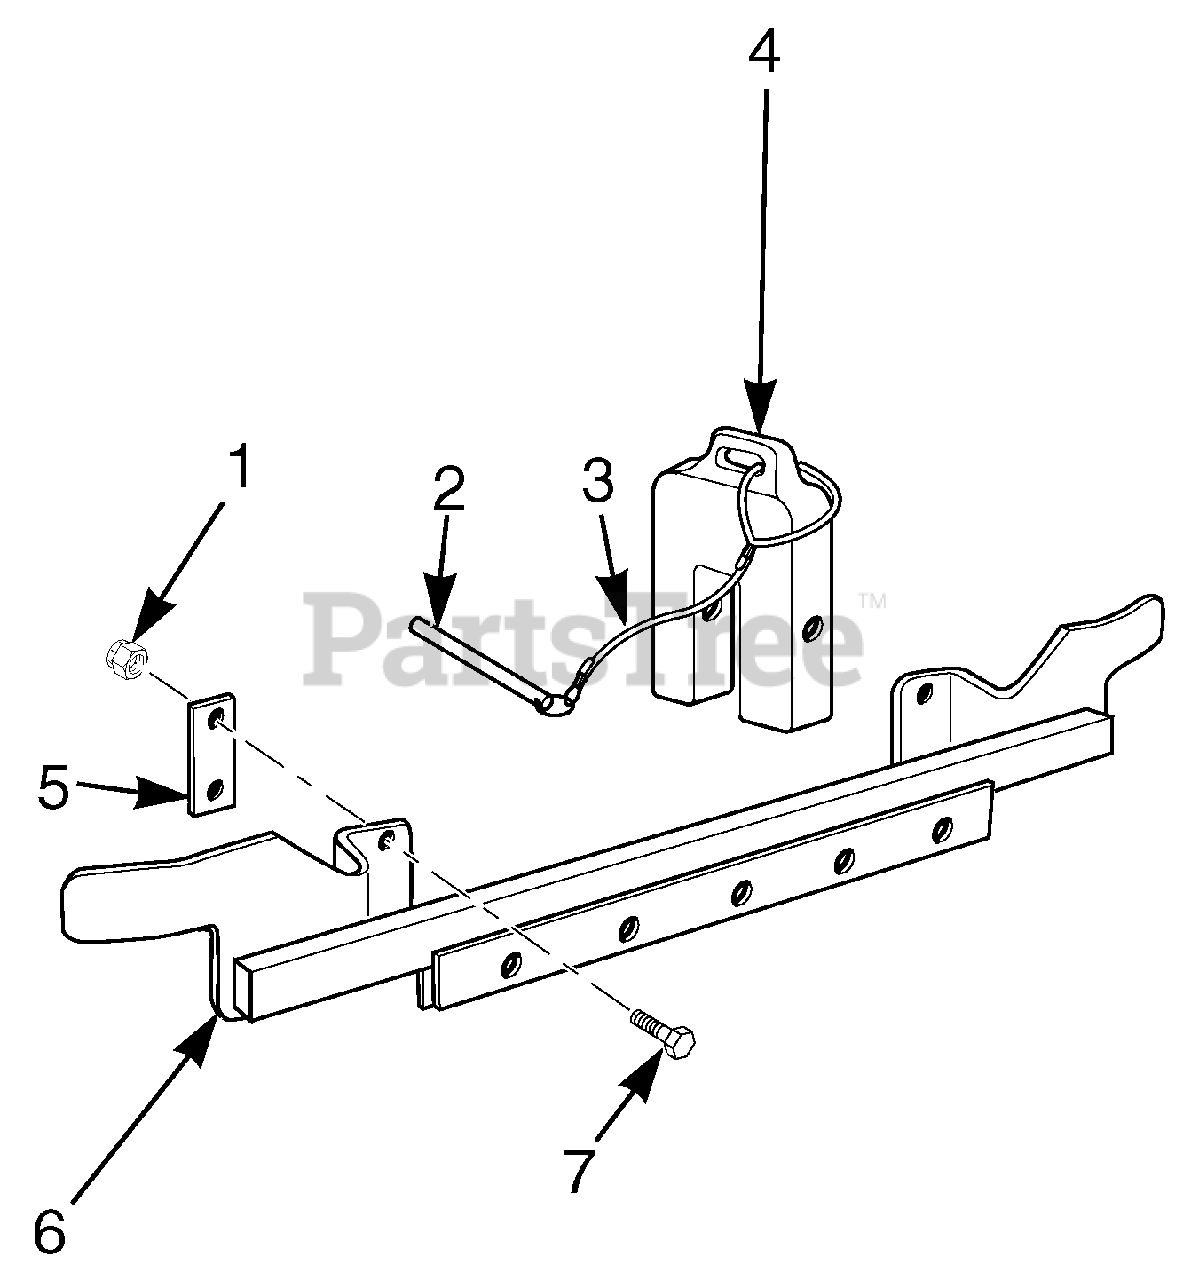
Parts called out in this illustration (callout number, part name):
1	Nut, Elastic Stop 3/8-16
2	Pin, 1/2 x 6-1/4"
3	Lanyard, Weight Pin
4	Weight Assembly
5	Clamp, Bar
6	Support Weldment, Front Weights
7	Bolt, Hex Head 3/8-16 x 1-1/2"
